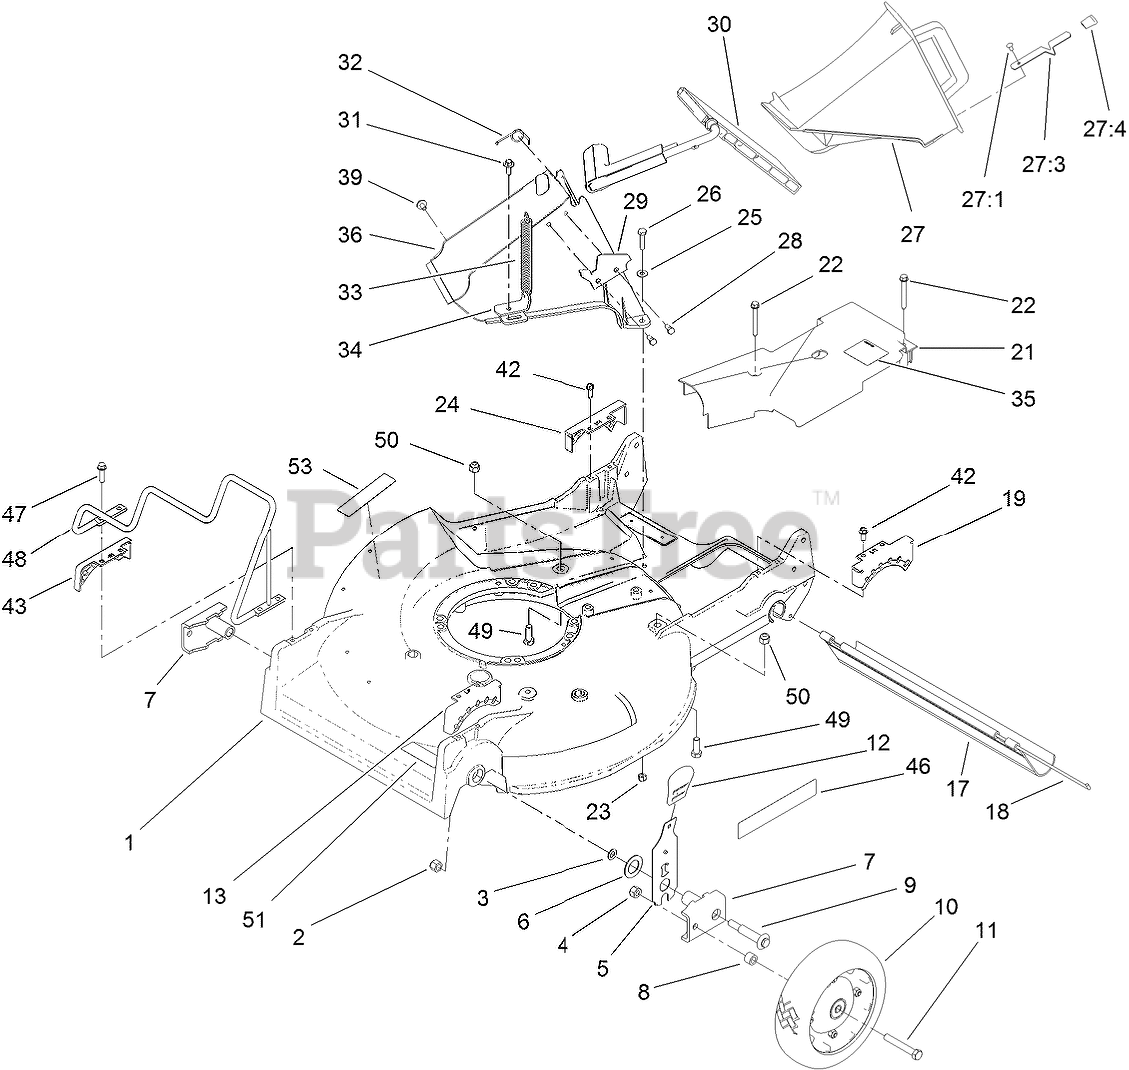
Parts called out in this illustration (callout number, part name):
1	HOUSING ASM
2	NUT-LOCK
3	WASHER
4	NUT-LOCK, CONE
5	FRONT SPRING ARM ASM
6	WASHER-THRUST
7	ARM-PIVOT, FRONT
8	SPACER-WHEEL
9	SCREW-SHOULDER
10	WHEEL AND TIRE ASM
11	SCREW-HH
12	KNOB-HOC
13	QUADRANT-FRONT, LH
17	SHIELD-TRAILING
18	ROD-SHIELD
19	QUADRANT-REAR, LH
21	COVER-BELT
22	SCREW-HWHTF
23	NUT-LOCK, NI
24	QUADRANT-REAR, RH
25	WASHER-FLAT
26	SCREW-HH
27	DISCHARGE PLUG ASM
27:1	RIVET-HEAD, FLAT
27:3	LATCH-PLUG, DISCHARGE
27:4	GRIP-LATCH
28	SCREW-PLASTITE
29	LATCH-PLATE
30	DISCHARGE DOOR ASM
31	SCREW-HWH
32	RETAINER-DOOR
33	SPRING-DOOR
34	BRACKET-SPRING
35	DECAL-GREASE
36	TUNNEL-DISCHARGE
39	SCREW AND WASHER ASM
42	SCREW-HWHTF
43	QUADRANT-FRONT, RH
47	SCREW-HWHTF
48	GUARD-ENGINE
49	SCREW-HH
50	NUT-LOCK, NI
51	DECAL-BLADE
53	DECAL-ARRESTER, SPARK
